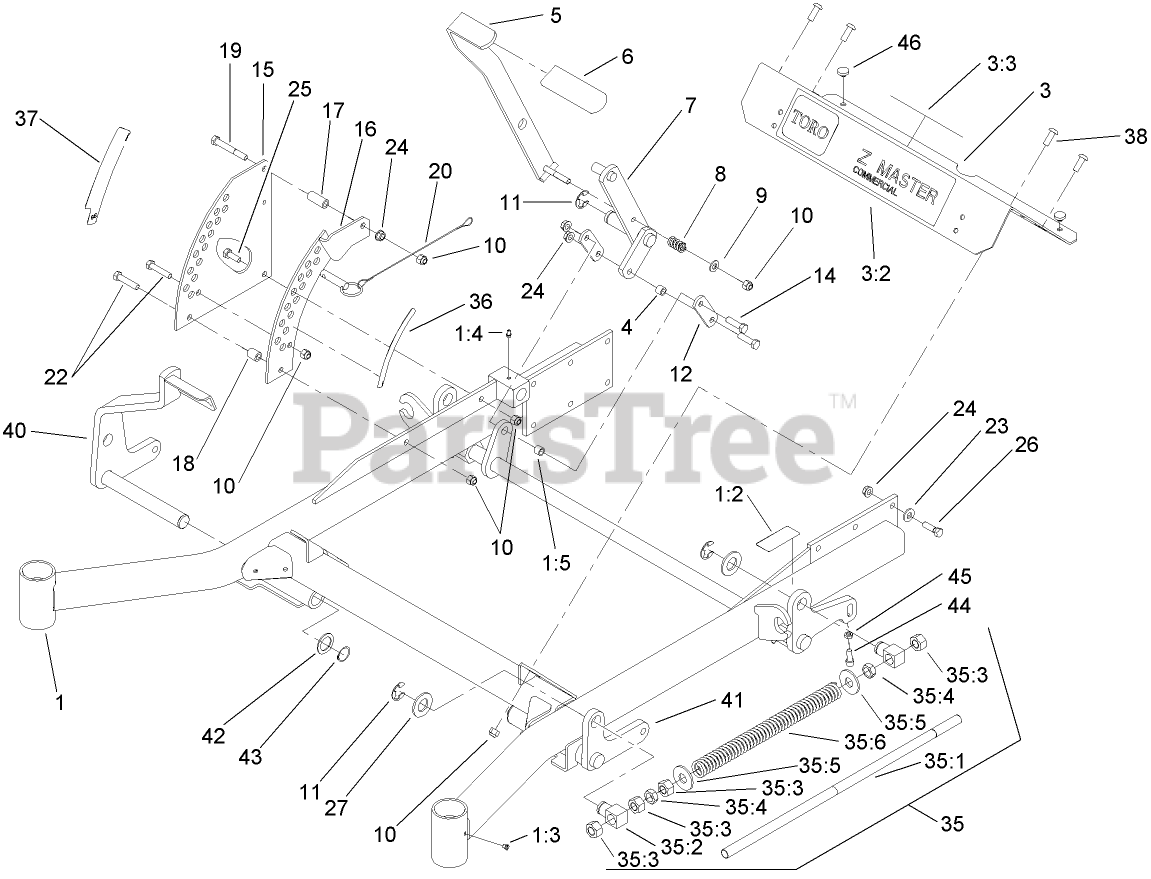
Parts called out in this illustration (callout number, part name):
1	FRAME ASM
1:2	Decal-Brake, Parking
1:4	FITTING-GREASE
1:5	Bushing
3	FOOTREST
3:3	DECAL-WARNING
4	Bushing
5	LEVER-LIFT
6	GRIP-LEVER, LIFT
7	ARM-LIFT, DECK
8	SPRING-COMPRESSION
9	WASHER-FLAT
10	NUT-LOCK, NI
11	RING-RETAINING, EXT
12	ARM-LIFT, DECK
14	SCREW-HH
15	PLATE-LIFT, DECK
16	PLATE-LIFT, DECK
17	BUSHING-LEVER, LIFT
18	BUSHING-LEVER, LIFT
19	SCREW-HH
20	Hitch Pin ASM
22	SCREW-HH
23	WASHER-BELLEVILLE
24	NUT-HHF, WHIZ
25	SCREW-HH
26	SCREW-HH
27	WASHER-FLAT
35	Front Frame Spring ASM
35:1	ROD-LIFT, DECK
35:2	SWIVEL-DECK MOUNT, REAR
35:3	NUT-HEX
35:4	NUT-JAM
35:5	WASHER-FLAT
35:6	SPRING-SUPPORT, DECK
36	Decal-Height, Deck
37	Decal-Height, Deck
38	SCREW-HSBH
40	RH Deck Lift ASM
41	LIFT-DECK, LH
42	WASHER-SPACER
43	RING-RETAINING
44	SCREW-HSH
45	NUT-JAM
46	BUMPER
